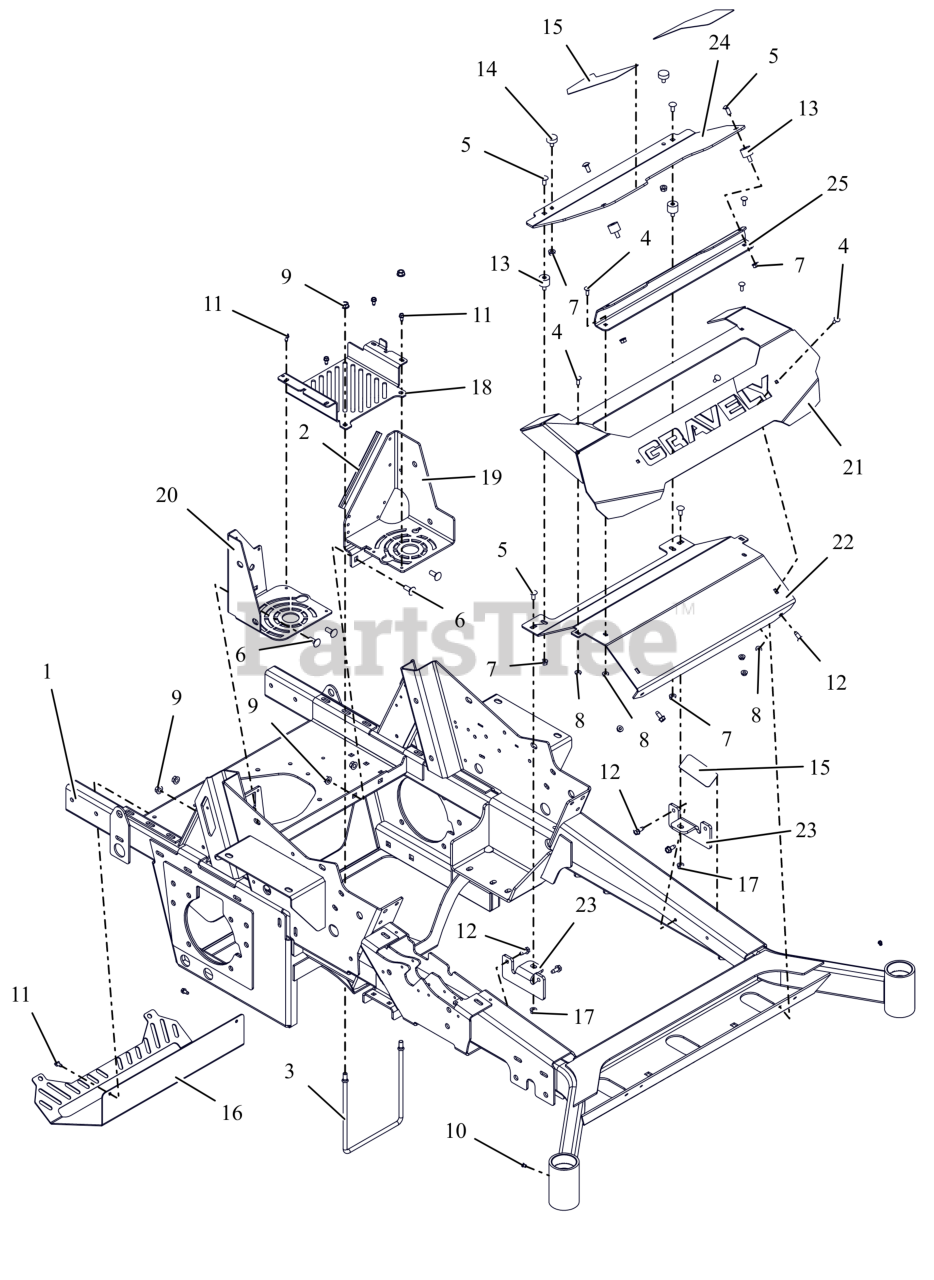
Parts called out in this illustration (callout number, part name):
1	WLDMT, MACH ONE, 72" FRAME (RED)
2	STRIP, COWL
3	ROD, BRAKE MTG
4	BLT, RHSN .25-20X.750 G5 ZCC
5	BLT, RHSSN.31-18X.750 G5 ZCC
6	BLT, RHSN .38-16X1.00 G5 ZCC
7	NUT,SPNLK-FLG .31-18 G5 ZCC
8	NUT-LK-CTR-FLG .25-20 ZC120
9	NUT-LK-CTR-FLG .375-16 GF ZCC
10	FTG, .25-28 FLUSH MNT GREASE
11	SCR-TAP .25-20X.50 HWH ZCC
12	SCR,TAP .312-18X.75 HWH TR ZCC
13	BUMPER,STUD MNTD W/FEMALE INSR
14	BUMPER, RUBBER
15	KIT, PT300-600 ANTI-SKID Tape
16	GUARD, MUFFLER (BLACK)
17	NUT,LK-CTR-FLG .31-18 GF ZCC
18	TRAY- BATTERY
19	GUSSET-LH BATTERY TRY/ROPS-RED
20	GUSSET- FAN GUARD/ROPS - RED
21	BMPR-PT300-500 FRT FTRST/ -RED
22	BRKT-FRT BUMPER MTG/BACKER-BLK
23	BRKT, FOOTREST MTG (RED)
24	FOOTREST, PT300-500 (RED)
25	BRKT, FOOTREST SUPPORT (BLK)
